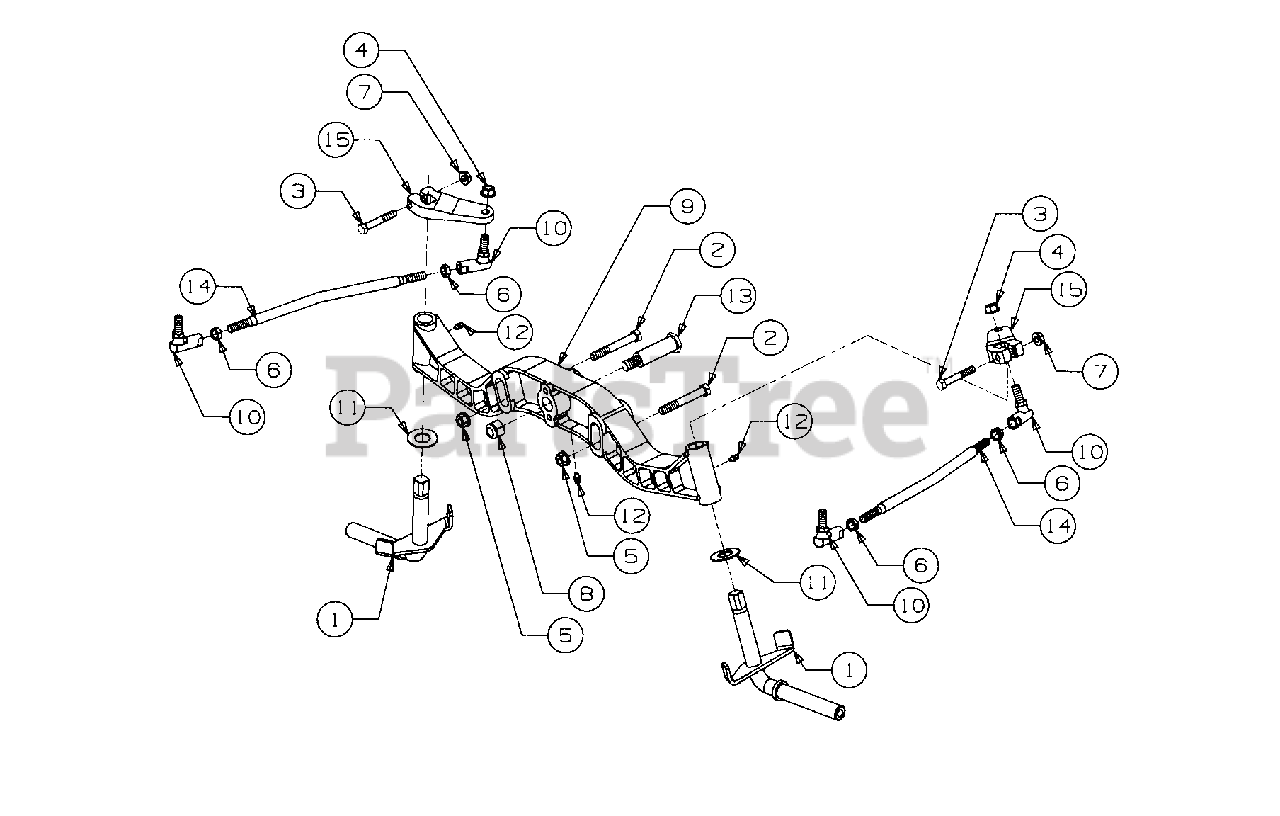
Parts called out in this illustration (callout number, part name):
1	Knuckle Assembly, Steering
2	Screw, Hex Cap, 3/8-16 x 2.75 GR8
3	Screw, Hex Cap, 5/16-18 x 2 GR5
4	Nut, Hex Lock, 3/8-24 GR5
5	Nut, Hex Flanged Lock, 3/8-16
6	Nut, Hex Jam, 3/8-24 GR5
7	Nut, Hex Flange Top Lock, 5/16-18
8	Nut, Hex Top Nylon Lock, 1/2-13
9	Axle, Front Pivot
10	Joint, Ball, 3/8-24
11	Washer, Flat, .760 x 1.49 x .06 Thk.
12	Fitting, Lube, 3/16 Drive Type
13	Bolt, Pivot Shoulder, 3/4 Dia x 2.23
15	Arm, Steering
